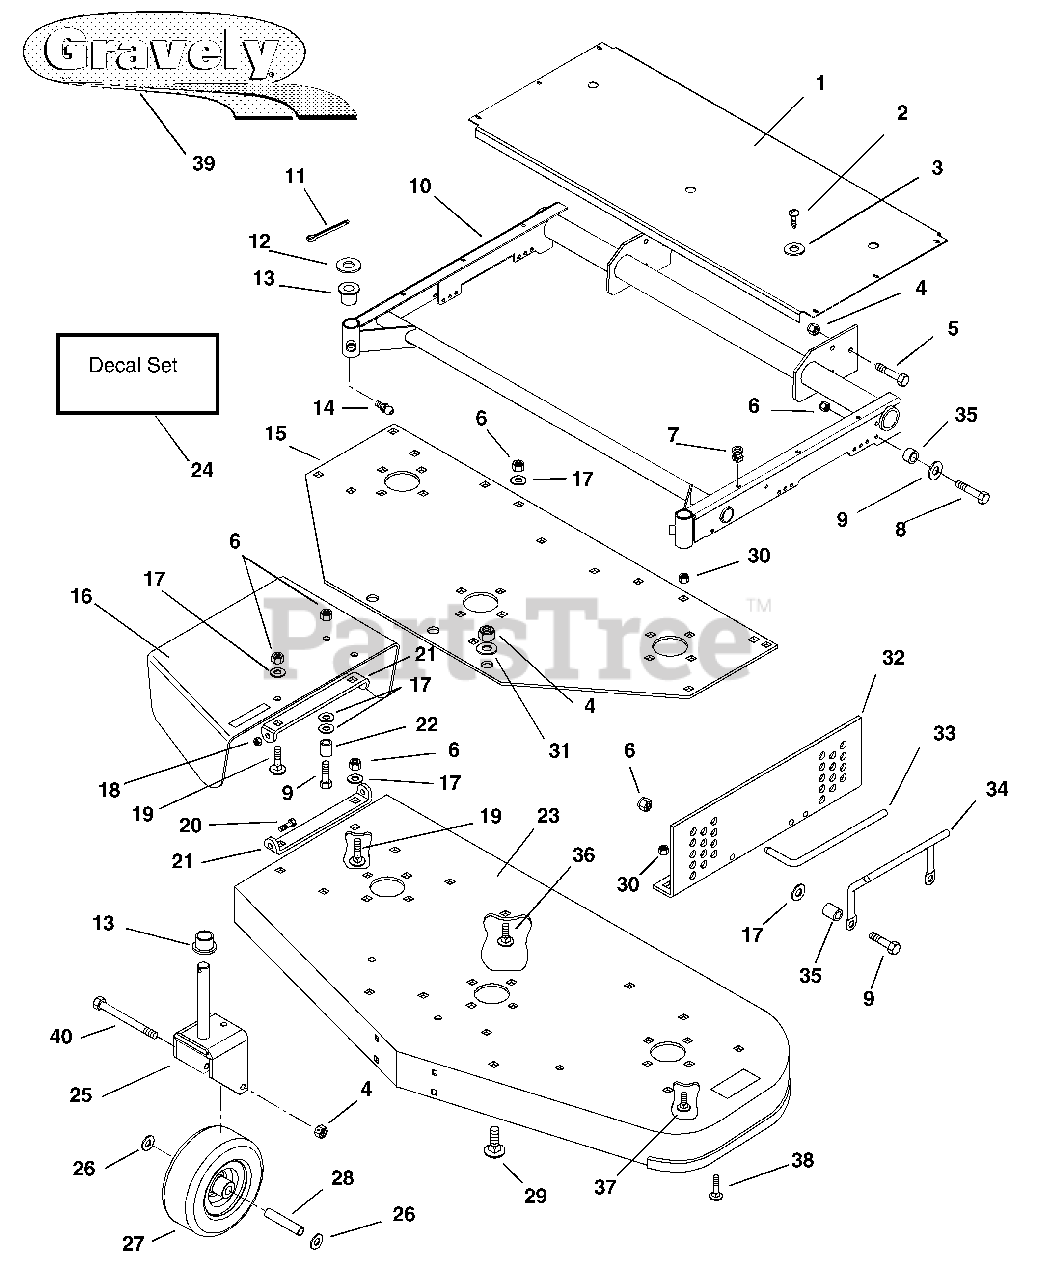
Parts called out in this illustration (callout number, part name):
1	Guard, 50"
2	Screw-Tapping, .25-20 x .50 Hex Slot Head
3	Washer-Flat-Steel .281 x .625 x .065
4	Nut, Locking .50-13
5	Bolt, Hex .50-13 x 1.50
6	Nut-Locking-Nylon .375-16 w/ Insr Grade 2
7	Grommet, Plastic
8	Bolt-Hex .38-16 x 1.50 Grade 5
9	Washer-Flat-Steel .390 x 1.5 x .125
10	Weldment, Mower Frame
11	Pin, Cotter .187 x 1.50
12	Race, Bearing Thrust
13	Bushing-Flange 1.03 x 1.75 x .750 Nylon
14	Fitting, Lube .25-28
15	Plate, Support
16	Shield, Safety Ext. 50" Mower
17	Washer-Flat-Steel .406 x .812 x .065
18	Nut, Locking .25-20
19	Bolt, Round Head Square Neck .375-16 x 1.00
20	Bolt, Hex .25-20 x .875
21	Bracket, Chute
22	Stop, Chute
23	Weldment, 50" Mower Fabricated
24	Decal, Deck Service Kit
25	Weldment, Caster Fork
26	Washer-Flat-Steel .812 x 1.496 x .134
27	Wheel, Gauge 9 x 3.50
28	Bearing, Gauge Wheel .750 x .532 x 3.97
29	Bolt, Round Head Square Neck .50-13 x 1.00
30	Nut, Locking .312-18 x .625
31	Washer-Flat-Steel 531 x 1.250 x .100
32	Bracket, Mower Side Support Left Hand
32	Bracket, Mower Side Support Right Hand
33	Pin, Mower Locking
34	Handle
35	Bushing
36	Bolt, Carriage .375-16 x .75
37	Bolt, Round Head Square Neck .312-18 x .625
38	Bolt, Carriage .312-18 x 1.00
39	Decal, Gravely Logo
40	Bolt, Hex .5-13 x 5.50
